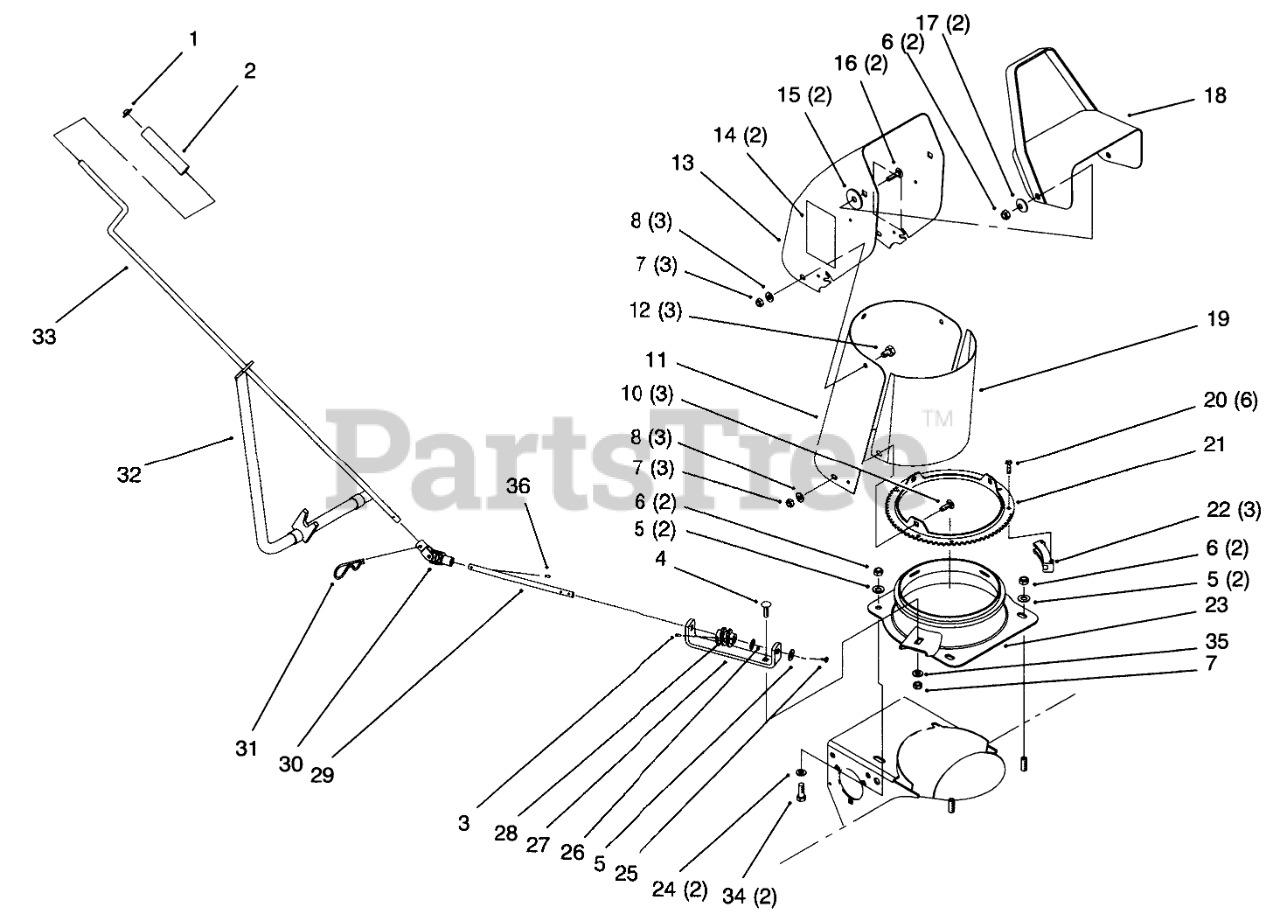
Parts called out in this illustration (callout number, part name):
1	RETAINER-PUSH ON
2	GRIP-CONTROL, CHUTE
3	PIN-SPRING
4	BOLT-CARR
5	WASHER-FLAT
6	NUT-LOCK, NI
7	NUT-LOCK, NI
8	WASHER-PLAIN
10	BOLT-CARR
11	EXTENDER-CHUTE, UPPER
12	SCREW-HH
13	Discharge Chute Asm (Incl. Ref. # 14)
14	Decal-Danger
15	WASHER-RUBBER
16	BOLT-CARR
17	WASHER-BELLEVILLE
18	DEFLECTOR
19	Shield-Deflector
20	SCREW-SPECIAL
21	CHUTE SWIVEL RING
22	RETAINER-CHUTE
23	ADAPTER
24	WASHER-SPACER
25	PIN-COTTER
26	WASHER-SPRING
27	BRACKET-WORM
28	GEAR-WORM, CHUTE
30	JOINT-UNIVERSAL
31	PIN-HAIR
32	Crank Support
33	ROD-CHUTE CONTROL
34	SCREW-HH
35	WASHER-LOCK
36	PIN-SPRING
